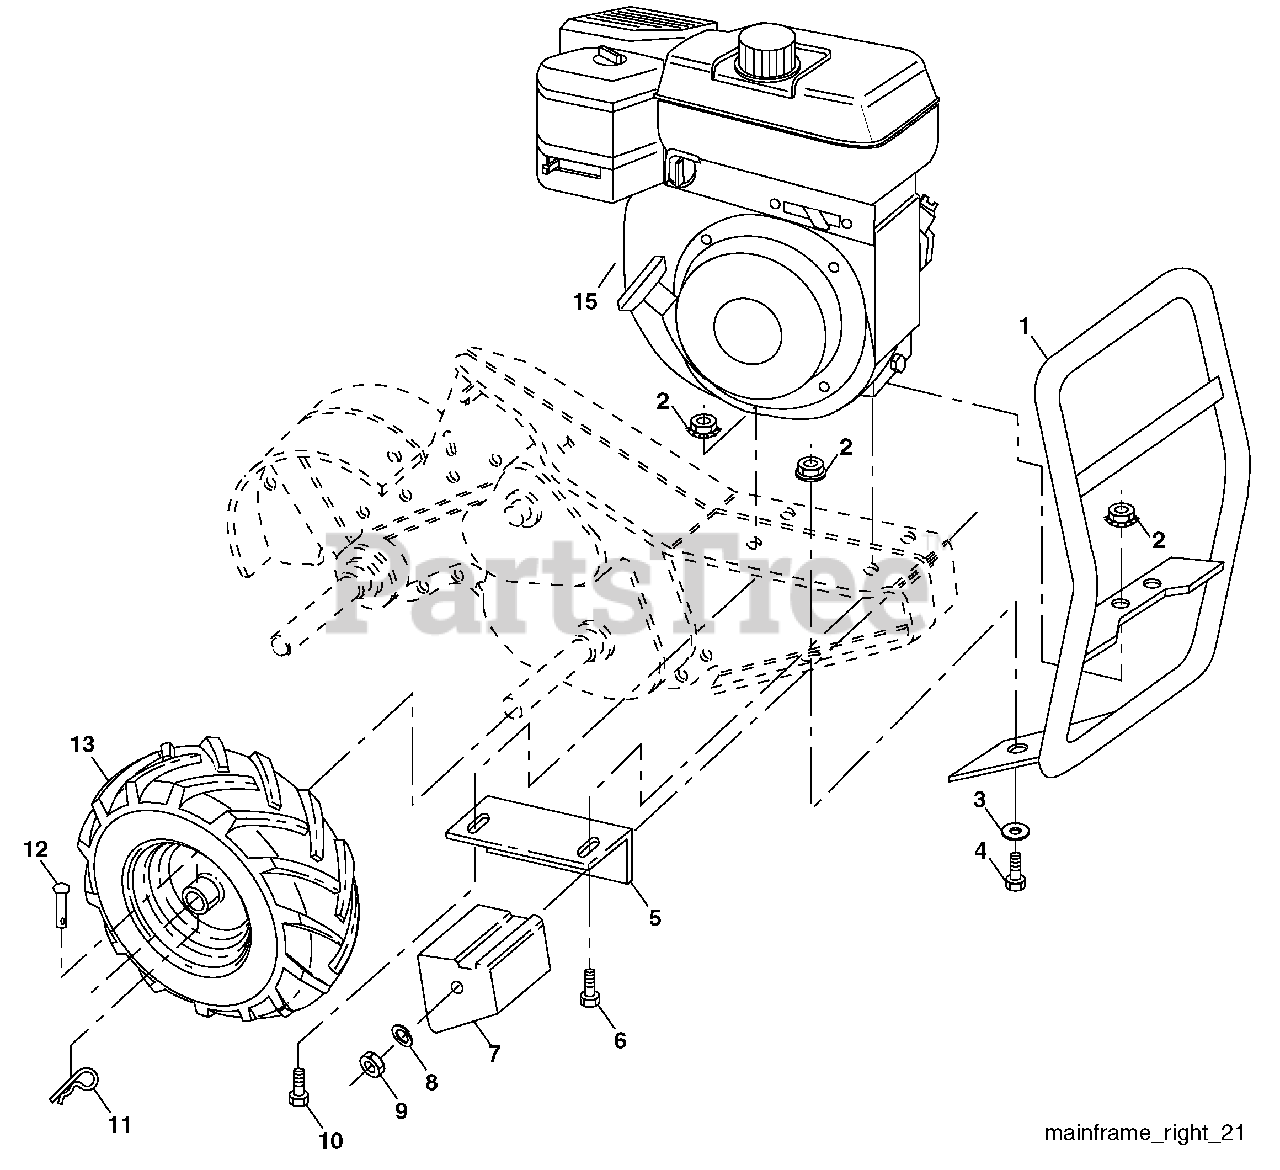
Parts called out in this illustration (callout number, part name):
2	Locknut, Hex, Flange 5/16-18
3	Washer 11/32 x 11/16 x 16 Ga.
4	Bolt, Hex 5/16-18 x 3/4
5	Bracket, Reinforcement
6	Bolt, Hex 5/16-18 x 1-3/4
7	Counter Weight, R.H.
8	Washer, Lock 3/8
9	Nut, Hex 3/8-16
10	Bolt, Hex 5/16-18 x 1-1/2
11	Clip, Hairpin
12	Rivet, Drilled
13	Tire
13	Rim
13	Tire Valve
